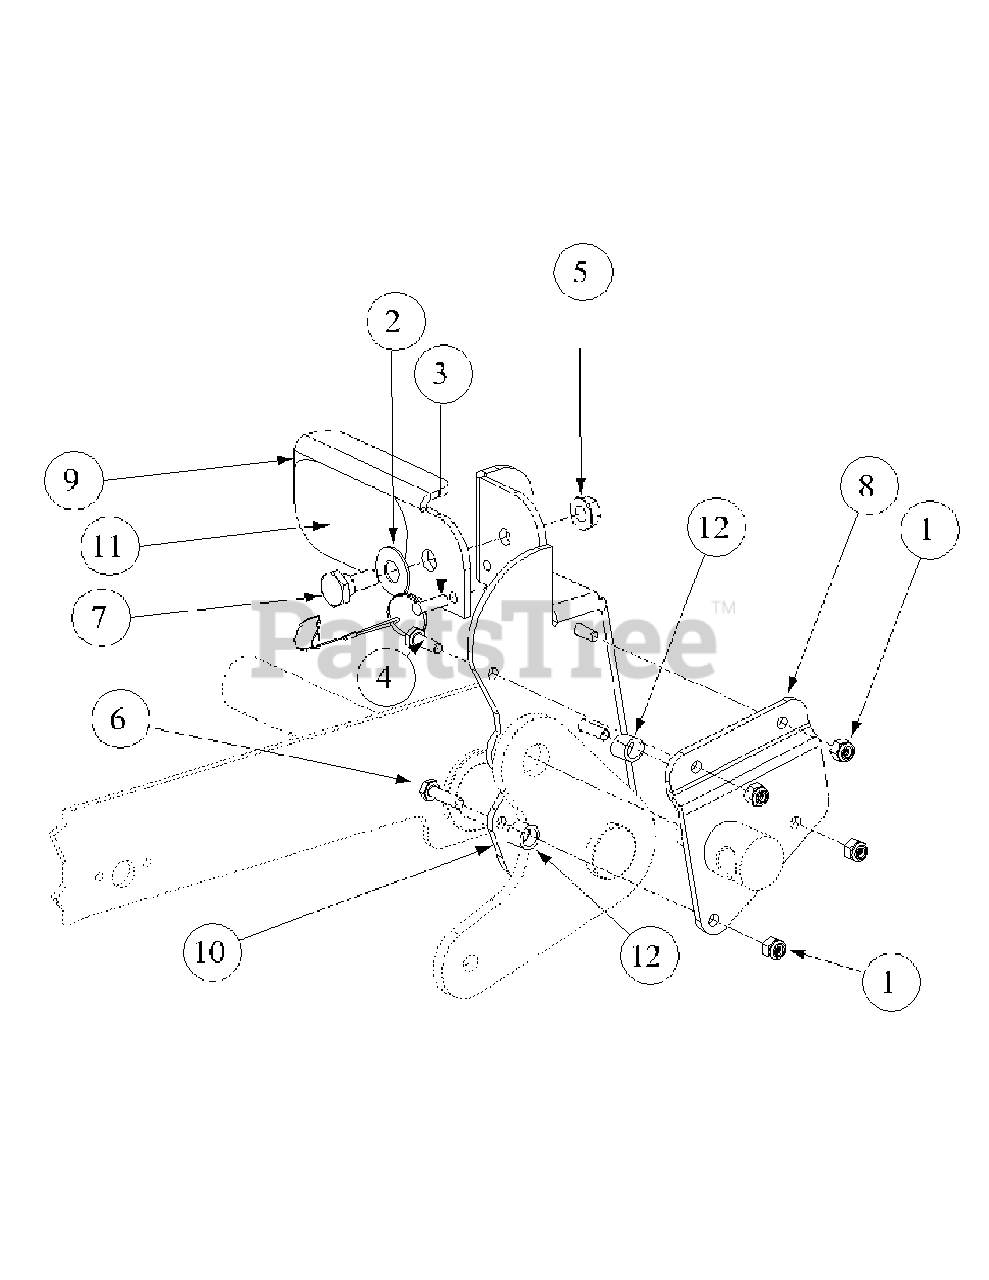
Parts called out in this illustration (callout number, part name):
1	Lock Nut, Nylon Insert, 1/4-20
2	Washer, 1/2 x 1 Shim
3	Detent Pin w/12" Lanyard
4	Hex Cap Screw, 1/4-20, .75
5	Hex Nut, Flange Lock 3/8-16
6	Hex Cap Screw, 1/4-20, 1.00
7	Shoulder Screw, .50 x .27 Lg., 3/8-16
8	Foot Lift Backup Pedal
9	Deck Lift Foot Pedal
10	Deck Lift Foot Pedal
11	Deck Lift Foot Pad
12	Turnbuckle Sleeve
